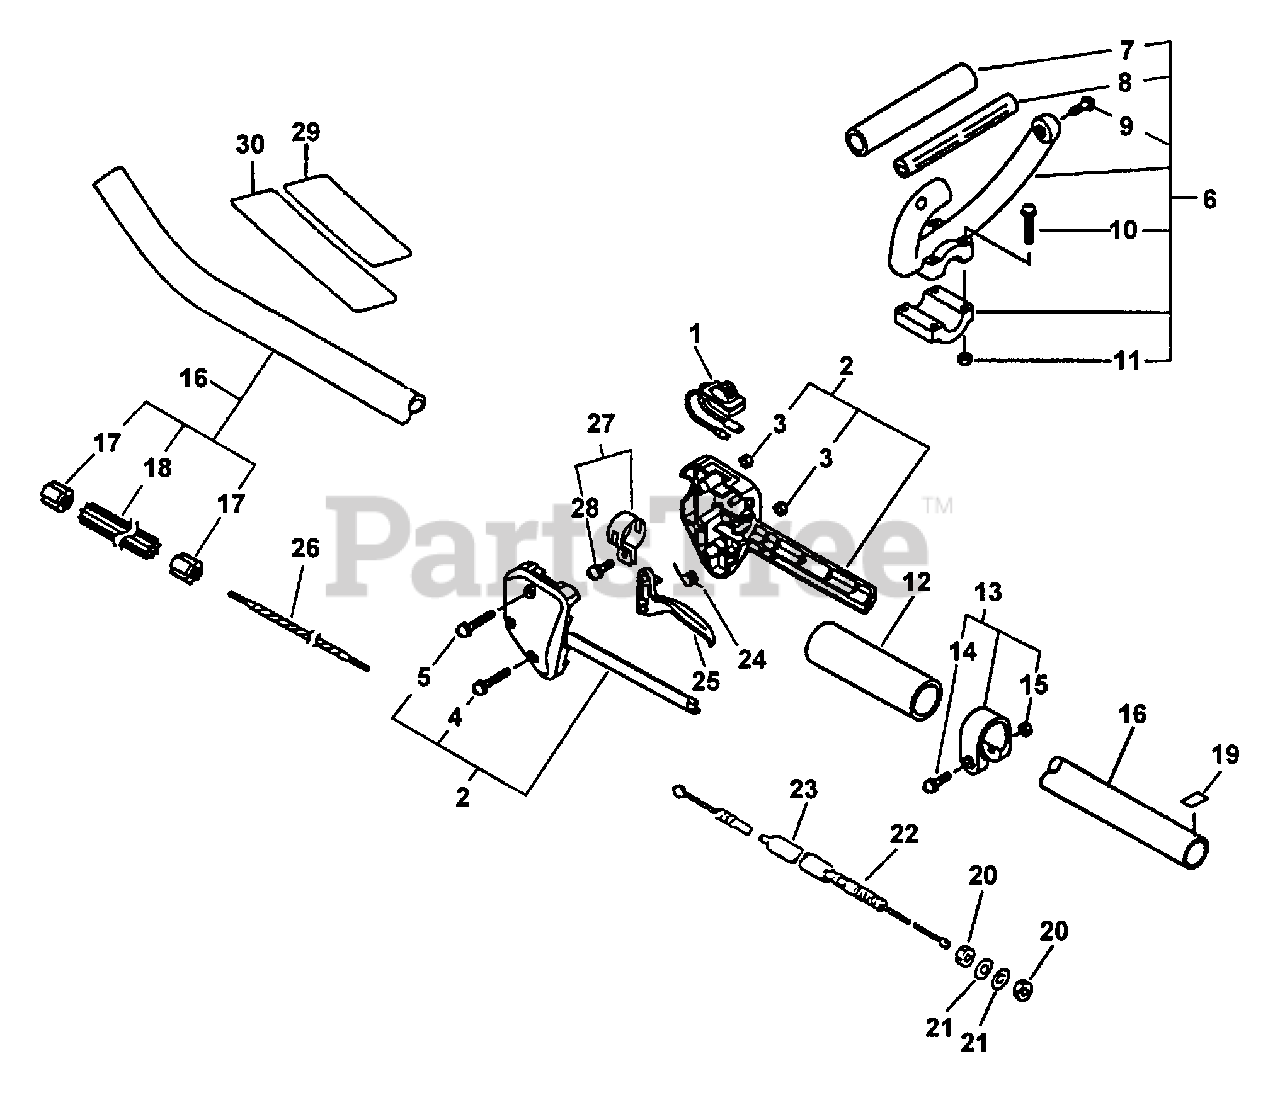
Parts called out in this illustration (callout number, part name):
1	IGNITION SWITCH ASSY
2	CONTROL HANDLE KIT
4	SCREW - 5X25
5	SCREW - 5X35
6	LOOP HANDLE ASSY
7	GRIP, HANDLE
9	SCREW - 5X30
10	SCREW - 6X35
11	LOCKNUT - 6
12	GRIP, HANDLE
13	CLAMP KIT
14	SCREW - 5X28
16	MAIN PIPE ASSY
18	LINER - FLEXIBLE
19	LABEL - ALIGNMENT
21	WASHER - 6
22	CABLE, THROTTLE
23	TUBE
24	SPRING, TRIGGER
25	TRIGGER, THROTTLE
26	DRIVESHAFT - FLEXIBLE
27	CLAMP KIT
28	SCREW - 5X14
29	LABEL - CAUTION
30	LABEL - CAUTION
